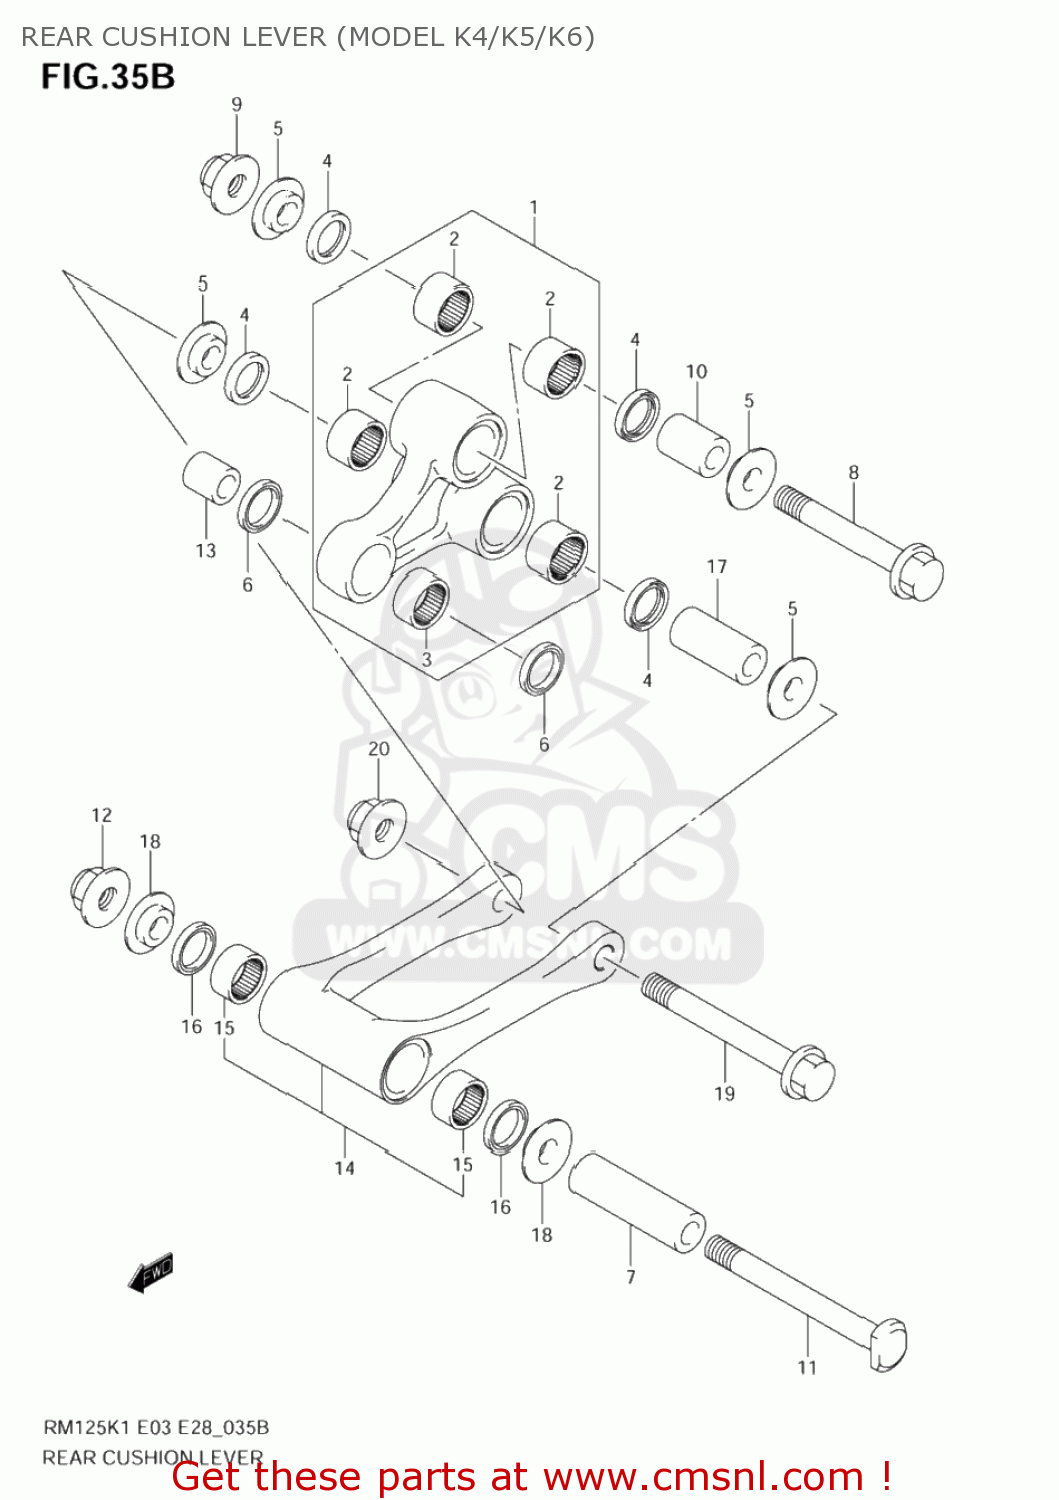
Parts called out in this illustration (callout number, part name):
1	LEVER SET,RR CUSHION
2	BEARING(20X26X14)
3	BEARING(20X26X12)
4	SEAL,OIL(20X26X4)
5	SPACER,RR CUSHION LEVER SIDE
6	SEAL,OIL(20X26X4.5)
7	SPACER,RR CUSHION ROD
8	BOLT,RR CUSHION LEVER UPR
9	NUT
10	SPACER,RR CUSHION
11	BOLT,RR CUSHION ROD
12	NUT
13	SPACER,RR CUSHION LEVER RR
14	ROD SET,RR CUSHION
15	BEARING(20X26X14)
16	SEAL,OIL(20X26X4)
17	SPACER,RR CUSHION LEVER LWR
18	SPACER,RR CUSHION LEVER SIDE
19	BOLT,RR CUSHION LEVER LWR
20	NUT
